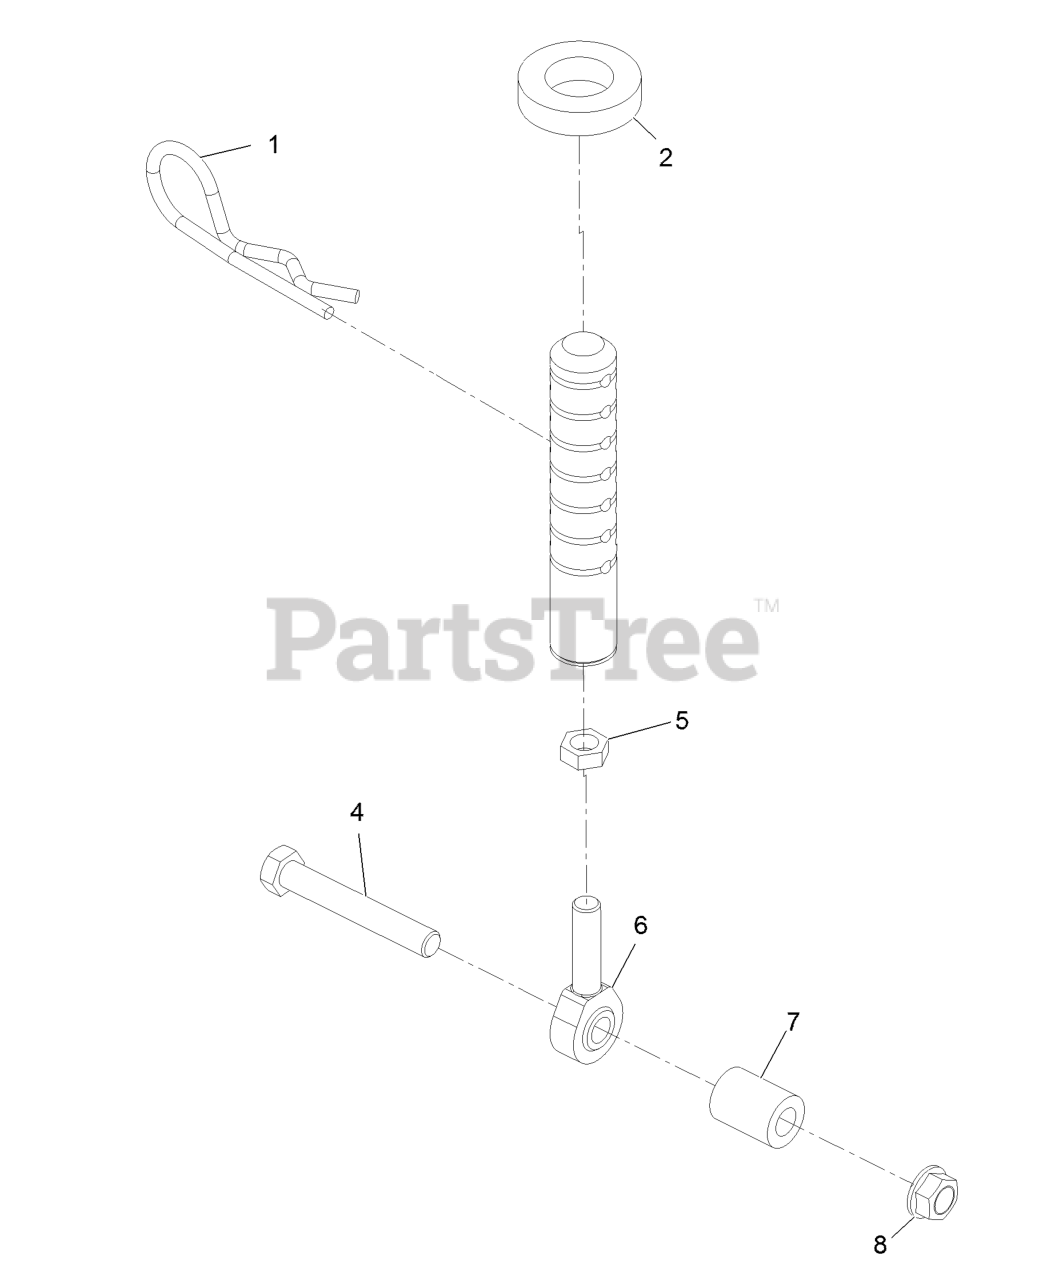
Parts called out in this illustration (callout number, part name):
1	PIN-CUT HEIGHT
2	SPACER-DECK SUPPORT
4	SCREW-HH
5	NUT-HJ
6	BALLJOINT
7	TUBE-INTERLOCK
8	NUT-HHF, WHIZ
